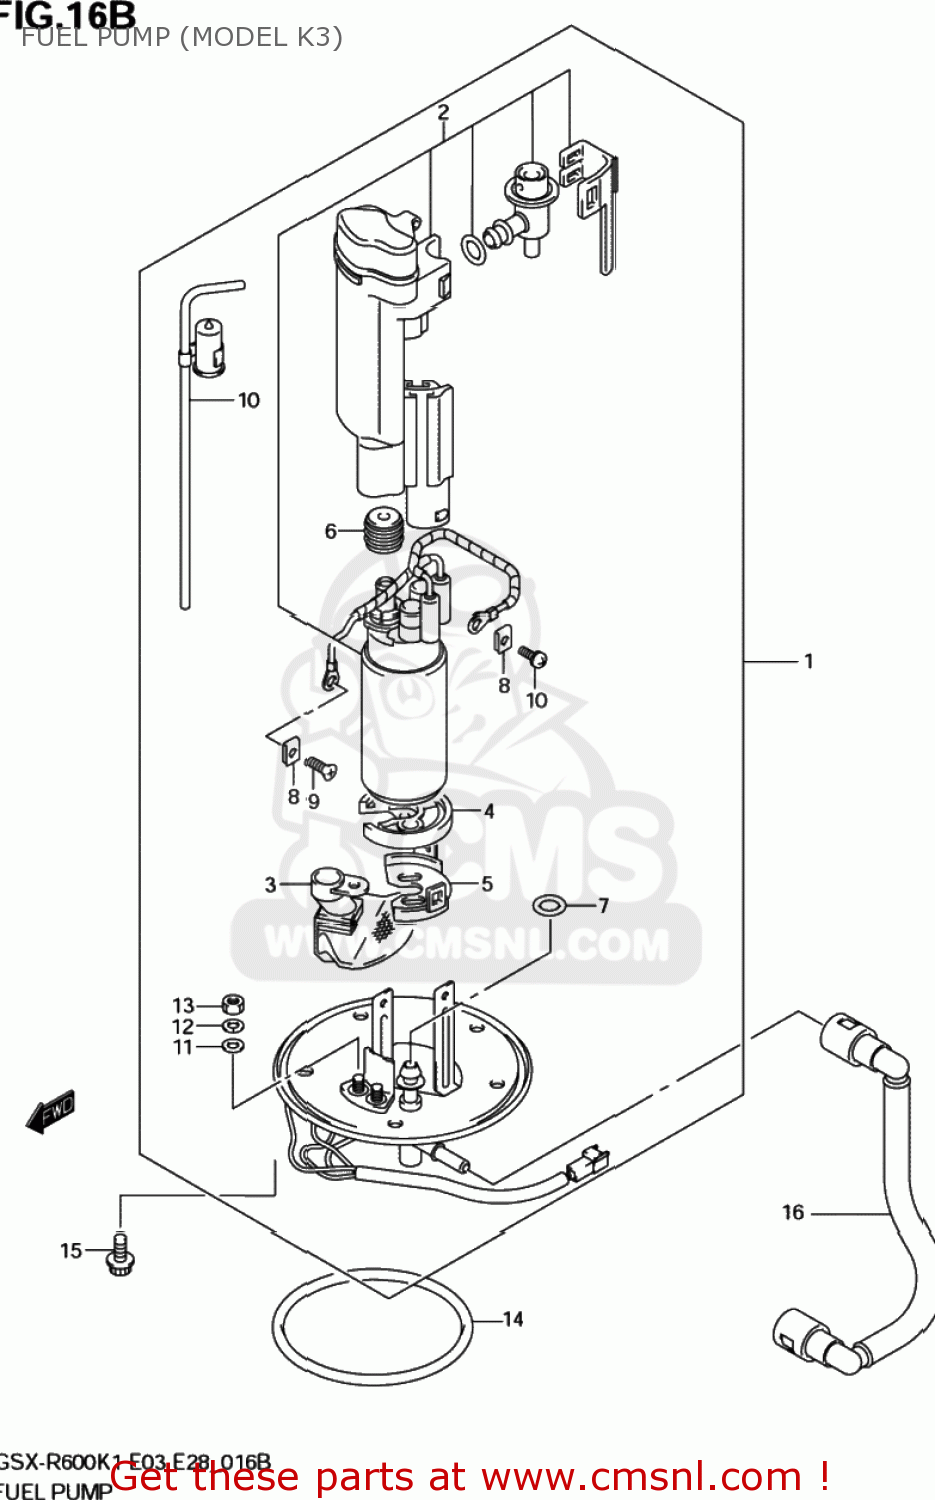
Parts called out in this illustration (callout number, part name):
1	PUMP ASSY,FUEL
2	FILTER ASSY,FUEL
3	STRAINER,FUEL PUMP
4	CUSHION
5	HOLDER,FUEL PUMP
6	BUSH,FUEL PUMP
7	O RING
8	NUT
9	SCREW
10	THERMISTOR
11	WASHER
12	WASHER,SPRING
13	NUT
14	O RING,FUEL PUMP
15	BOLT
16	HOSE,FUEL
